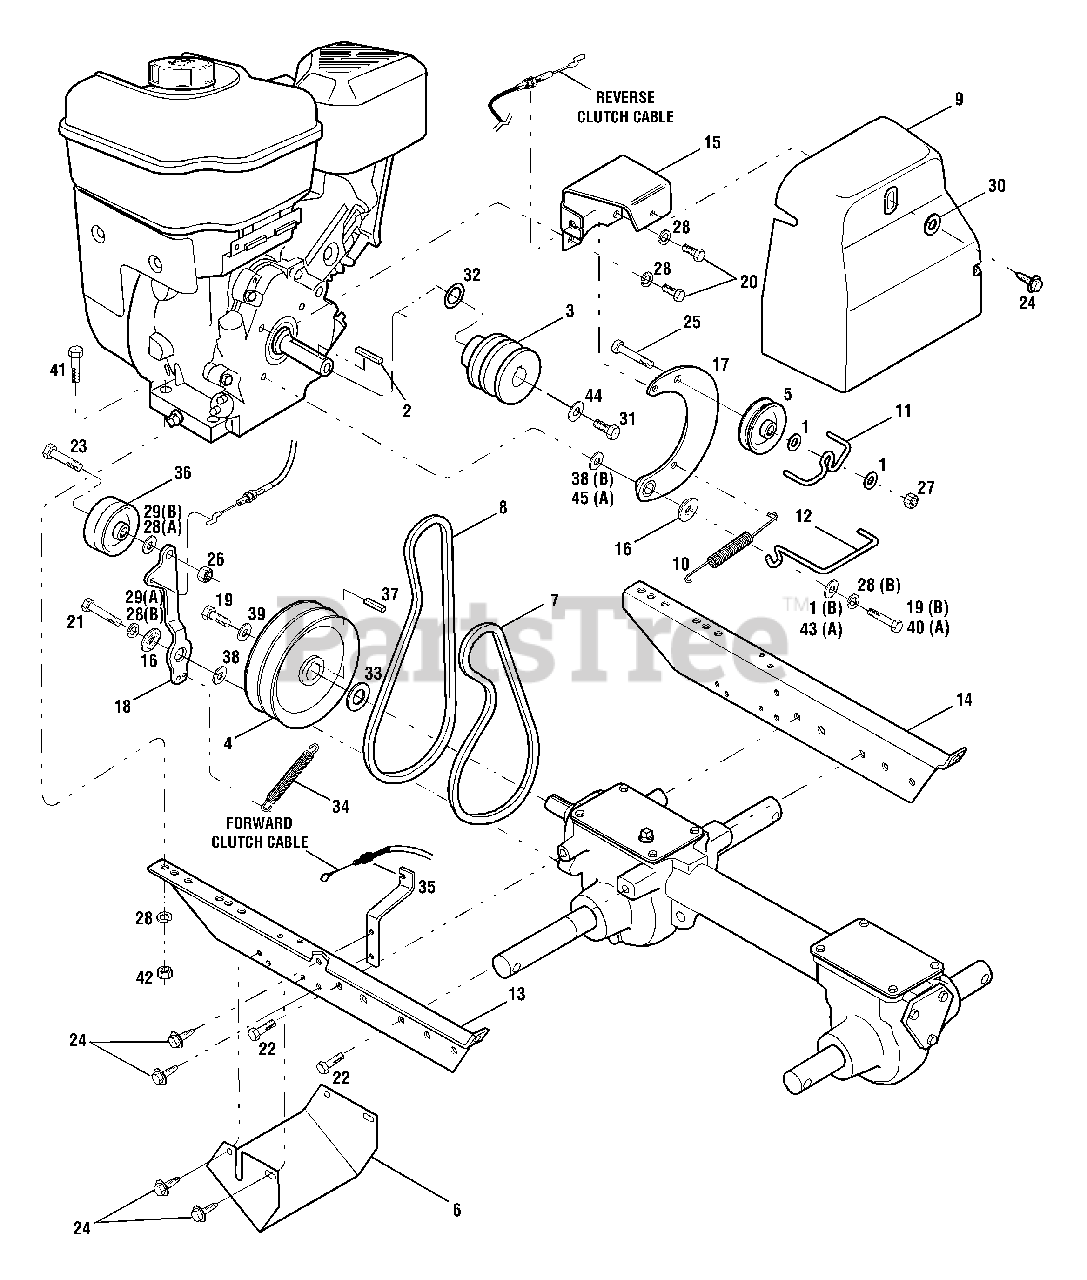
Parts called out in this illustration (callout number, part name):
1	Flat Washer, 5/16
2	Key, 3/16" x 2"
3	Pulley, Engine Drive
4	Transmission Pulley
5	Pulley, Reverse Idler
6	Guard, Belts/Pulleys
7	Forward Drive Belt
8	Reverse Drive Belt
9	Belt Cover
10	Reverse Return Spring
11	Reverse Belt Guide
12	Forward Belt Guide
13	Engine Bracket, Left
14	Engine Bracket, Right
15	Bracket, Belt Cover
16	Shoulder Washer
17	Reverse Idler Arm
18	Forward Idler Lever
19	Hex Hd. Screw, 5/16-24 x 1
20	Hex Hd. Screw, 5/16-24 x 5/8
21	Hex Hd. Screw, 5/16-18 x 1
22	Hex Hd. Screw, 5/16-18 x 5/8
23	Hex Hd. Screw, 3/8-16 x 1-1/2
24	Screw, Self-Tapping, 1/4-20 x 1/2
25	Hex Hd. Screw, 5/16-18 x 2
26	Lock Nut, 3/8-16
27	Lock Nut, 5/16-18
28	Lock Washer, 5/16
29	Flat Washer, 3/8
30	Flat Washer
31	Hex Hd. Screw, 3/8-24 x 2.00
32	Shim
33	Support Washer
34	Forward Return Spring
35	Bracket, Cable Mounting
36	Forward Idler Pulley
37	Key, 3/16" x 1"
38	Flat Washer
39	Belleville Washer
40	Hex Hd. Screw, 5/16-24 x 1.25
41	Hex Hd. Screw, 5/16-18 x 1-1/2
42	Hex Nut, 5/16-18
43	Bell Washer,.340 x.872 x.060
44	Bell Washer,.396 x 1.140 x.095
45	Spacer,.315 x.750 x 375 Lg
